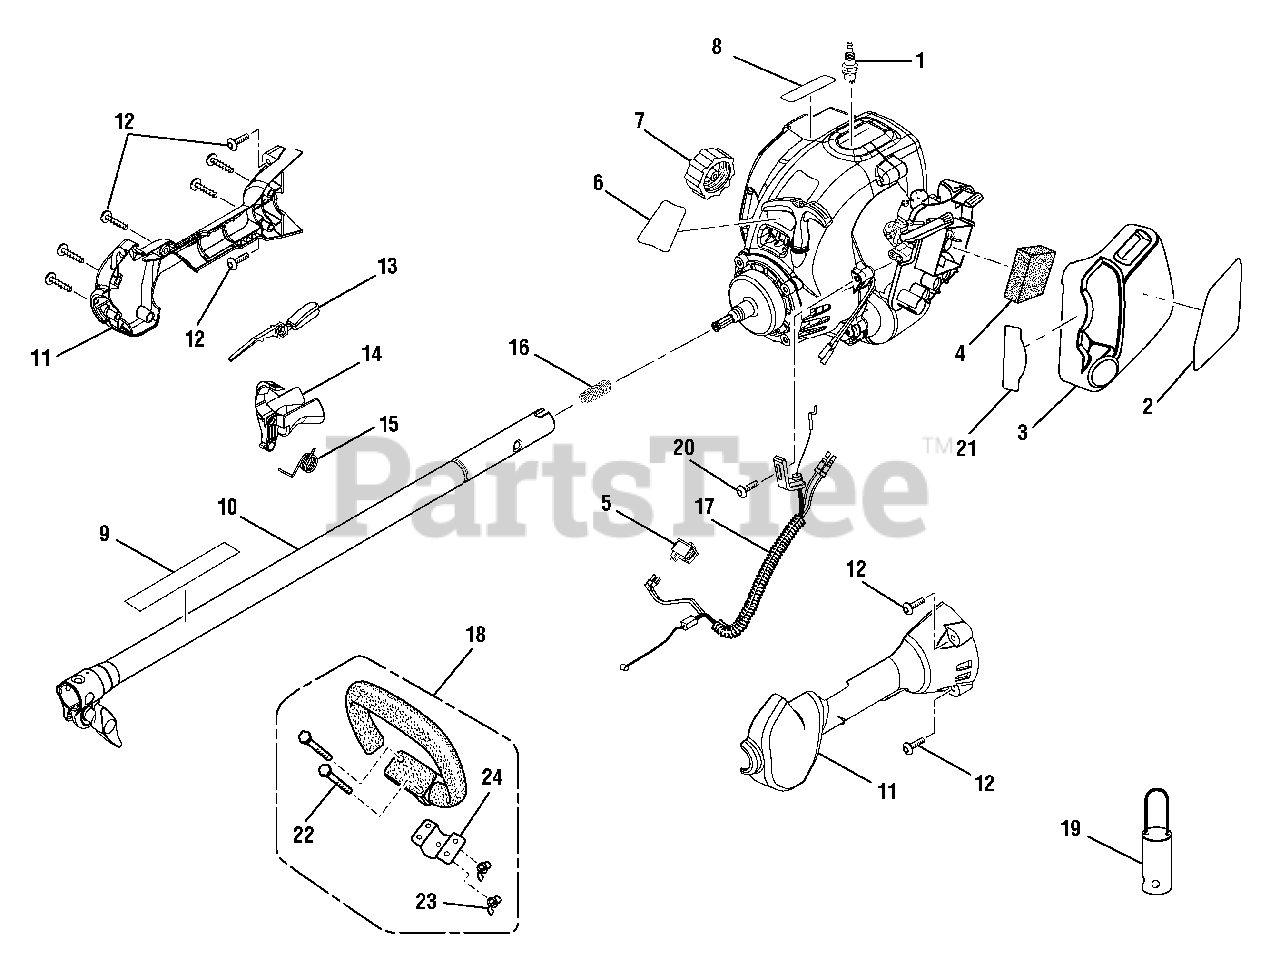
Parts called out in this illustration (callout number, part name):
1	Spark Plug (Champion RCJ4)
2	Starting Label
3	Air Box Cover
4	Air Filter Element
5	Switch (Momentary Contact)
6	Model Label
7	Fuel Cap Assembly
8	Logo Plate
9	Warning Decal
10	Upper Boom Assembly
11	Control Handle Assembly
12	Screw (10-14 x 1 in.)
13	Trigger Lock
14	Trigger
15	Torsion Spring
16	Compression Spring
17	Throttle and Lead Assembly
18	Front Handle Assembly
19	Hanger Cap
20	Screw (10-24 x 7/8 in.)
21	Choke Label
22	Bolt (M5 x 30 mm Hex Hd.)
23	Wing Nut (M5)
24	Handle Bar Clamp
